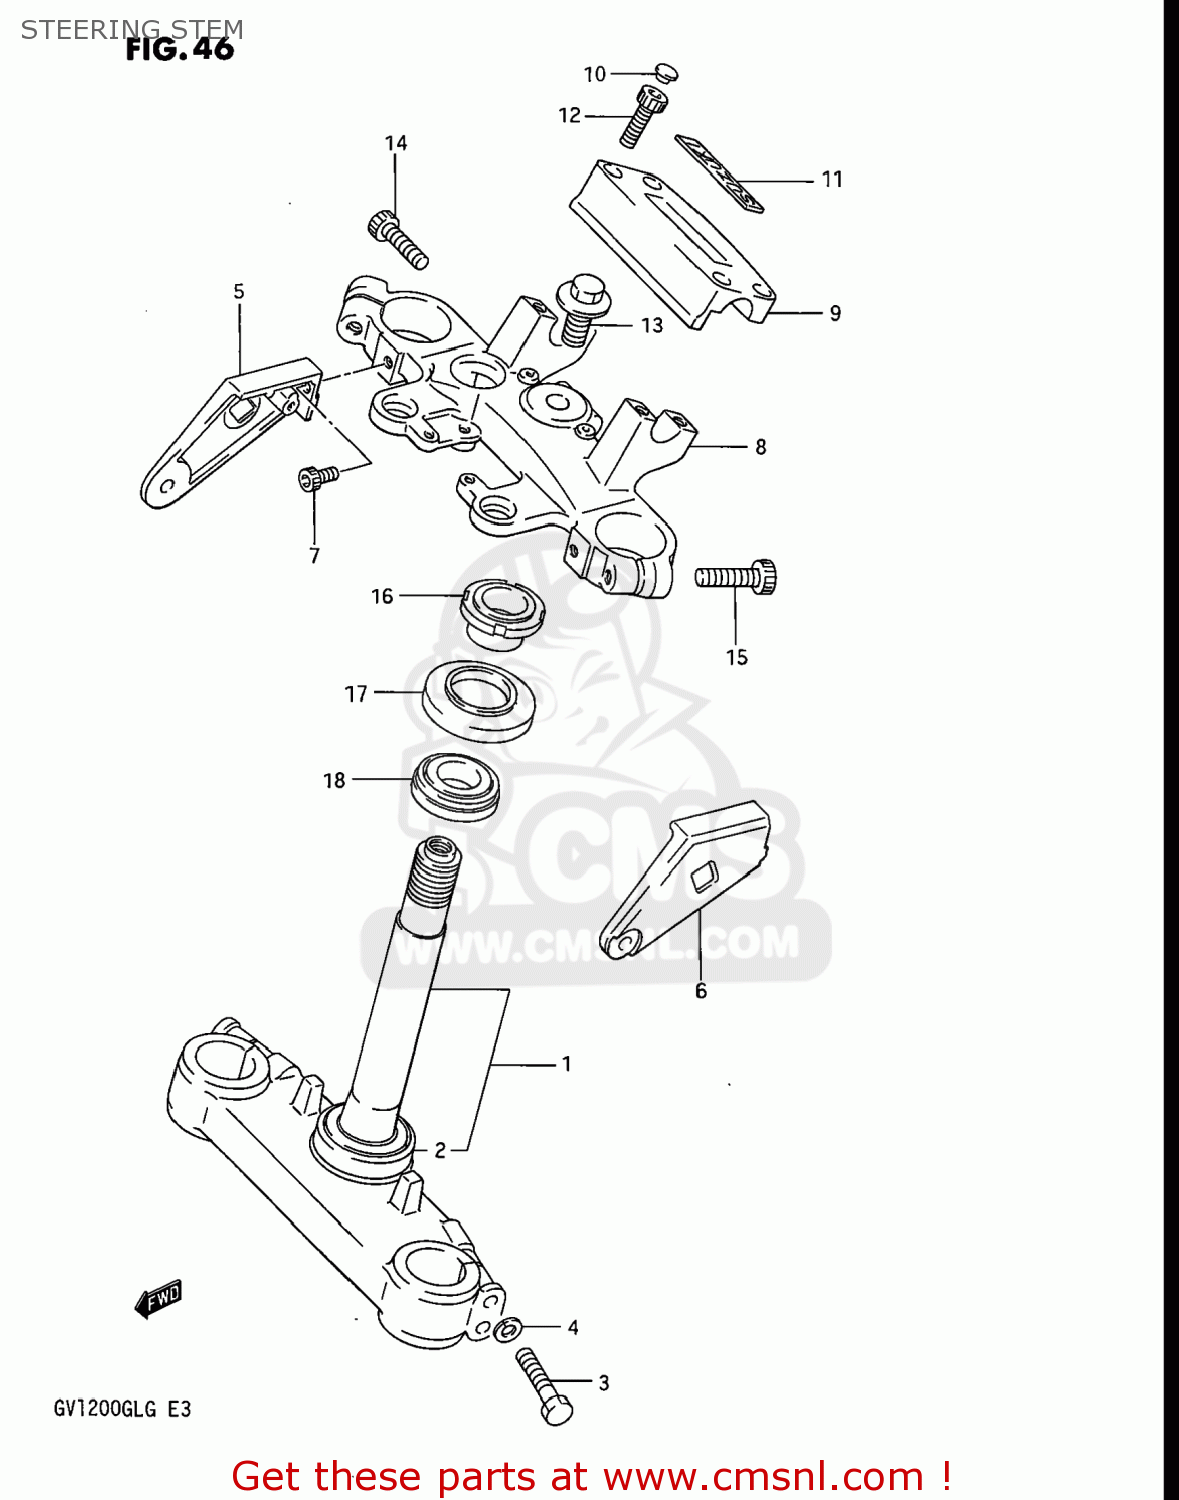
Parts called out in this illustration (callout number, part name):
1	STEM,STEERING
2	BEARING
3	BOLT
4	LOCK WASHER
5	BRACKET COMP,HEADLAMP
6	BRACKET,HEADLAMP,LEFT
7	BOLT
8	HEAD,STEERING STEM
9	HOLDER,HANDLEBAR
10	CAP(OD:14.5)
11	EMBLEM
12	BOUT
13	BOLT
14	BOLT 8X35
15	BOLT,STEERING STEM HEAD
16	NUT,STEERING STEM
17	DUST SEAL,STEERING UPR
18	TAPER,ROLLER BEARING
